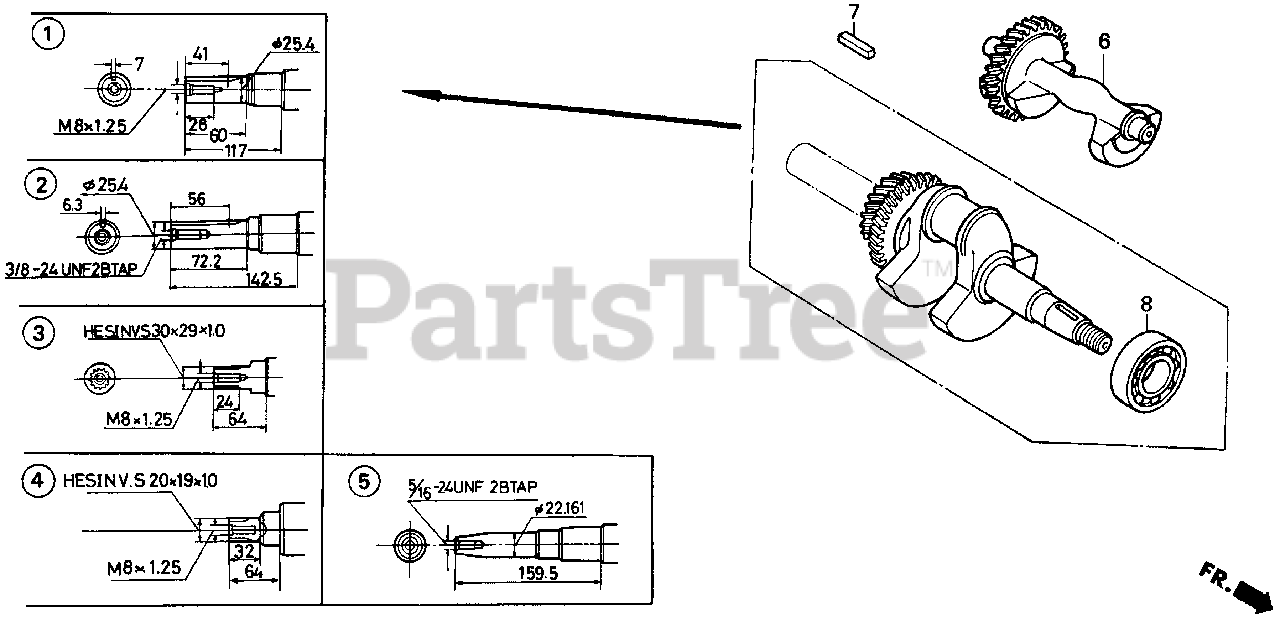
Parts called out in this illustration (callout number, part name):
2	CRANKSHAFT (Q-TYPE)
6	WEIGHT, BALANCER
7	KEY (6.3X6.3X43)
8	BEARING, RADIAL BALL (6207)
